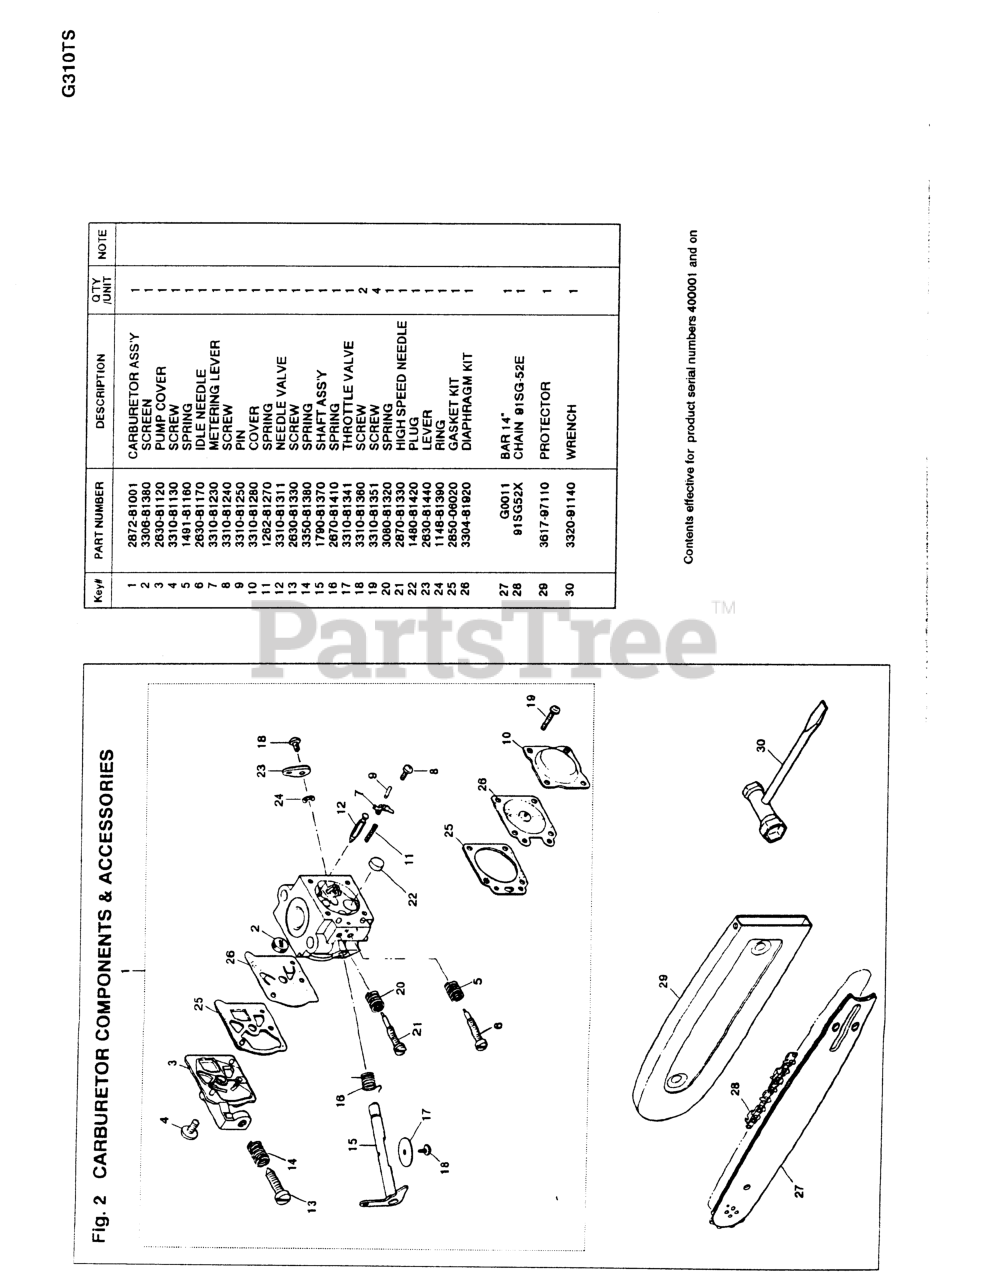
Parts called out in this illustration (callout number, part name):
1	CARBURETOR
7	LEVER
9	PIN, METERING LEVER
11	KIT ONLY
14	SPRING, IDLE
15	SHAFT, THROTTLE
16	SPRING, RETURN
19	SCREW ASSEMBLY
22	PLUG, WELSH
27	BAR 14
29	PROTECTOR (14.5
30	WRENCH, PLUG
